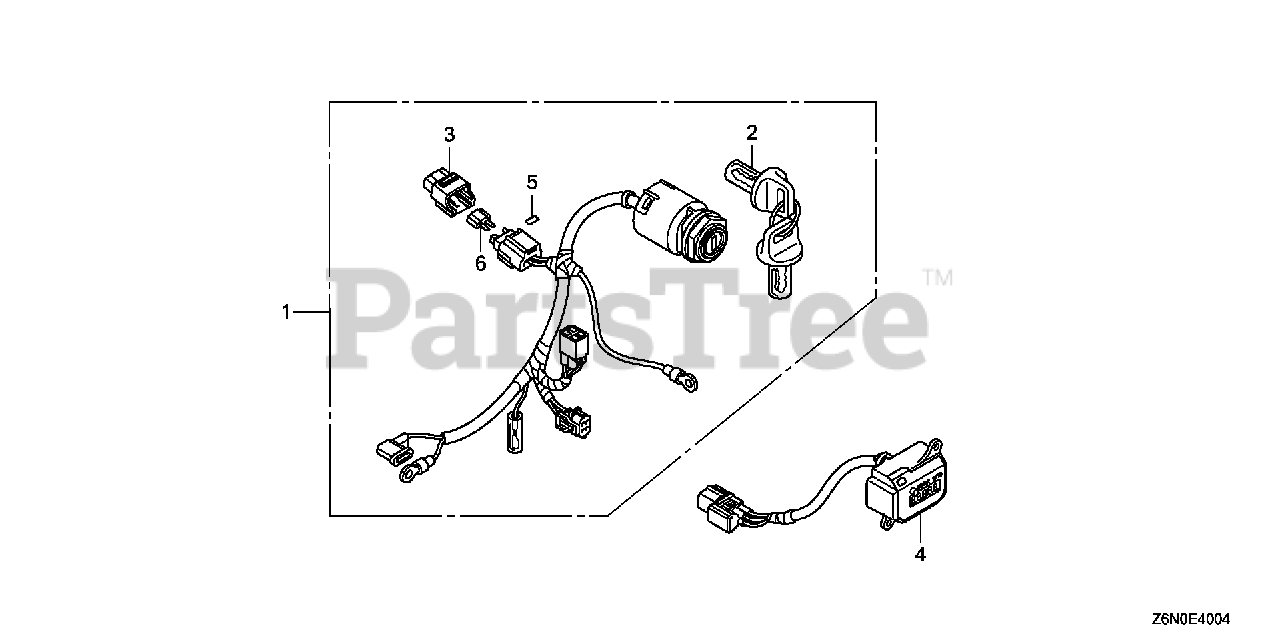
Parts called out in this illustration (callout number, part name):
1	SWITCH ASSY., COMBINATION
2	KEY ASSY., COMBINATION SWITCH (W05)
3	COVER ASSY., FUSE
4	METER ASSY., HOUR
5	LABEL, FUSE (30A)
6	FUSE, MINI (30A)
